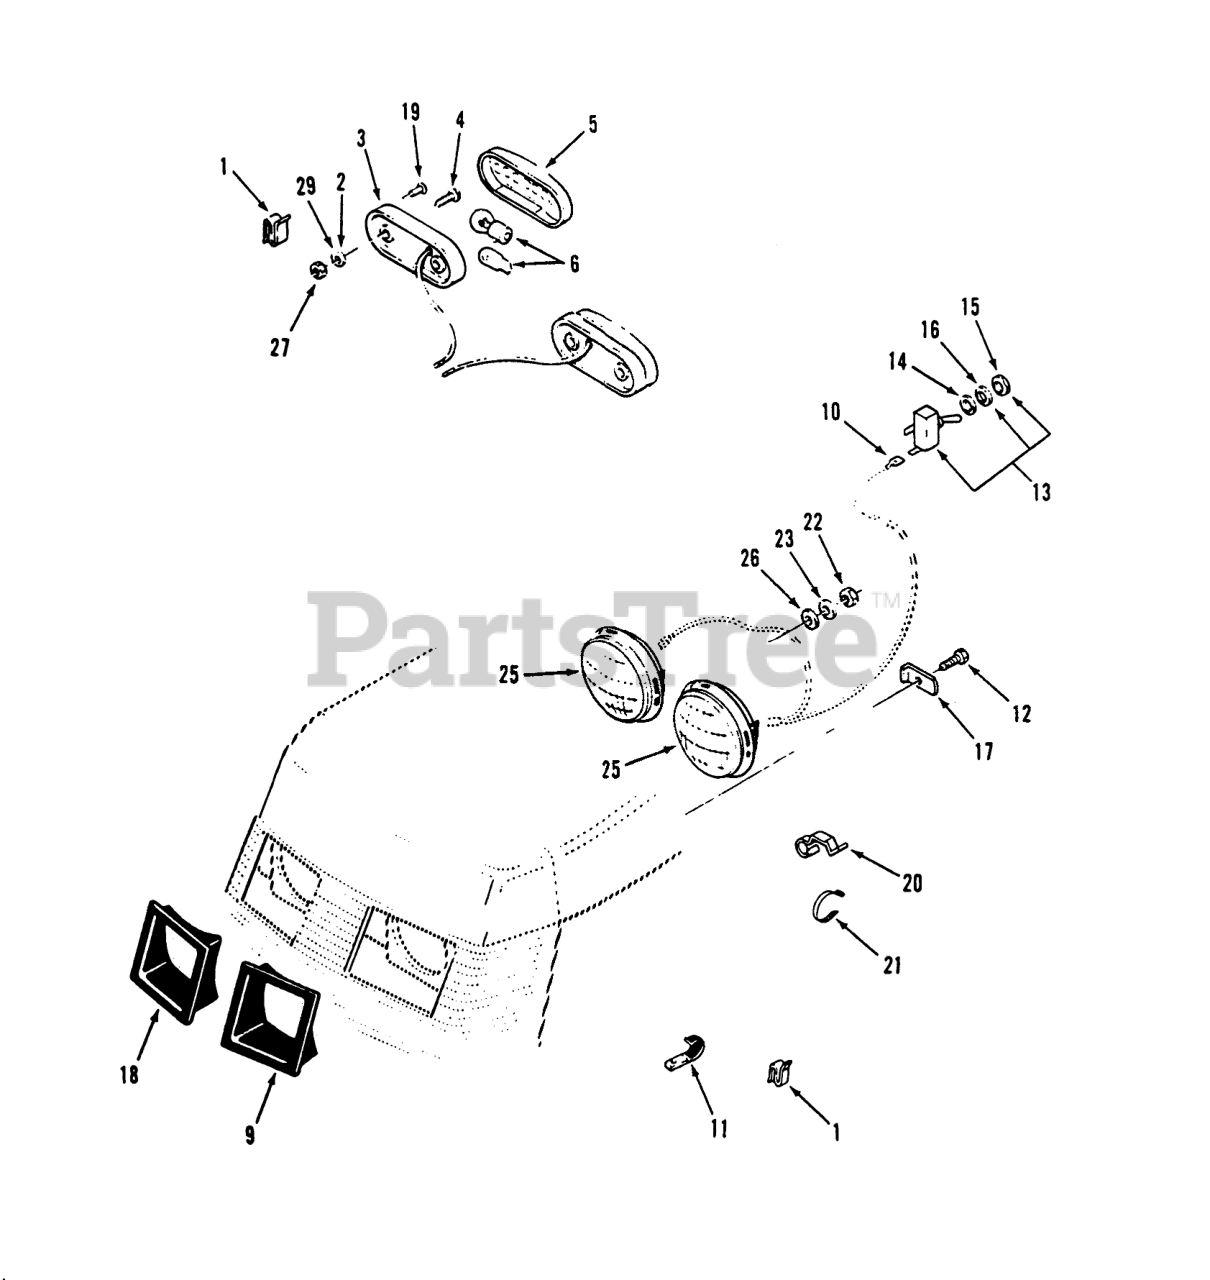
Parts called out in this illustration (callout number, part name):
1	SPEED CLIP
2	WASHER-LOCK
3	BASE-TAIL LIGHT
4	Screw
5	LENS-TAIL LIGHT
6	Bulb
9	BEZEL-HEADLIGHT, LH
10	Terminal
11	CLIP
12	Bolt
13	SWITCH-LIGHTS
14	Washer
16	TAB-WASHER
17	LOCK-HEADLIGHT
18	BEZEL-HEADLIGHT, RH
19	RIVET-POP
20	CLIP-WIRE
21	PLASTIC TIE
22	NUT-LOCK, NI
23	WASHER-LOCK, INTERNAL
25	HEADLAMP
26	WASHER-PLAIN
27	Nut
29	WASHER-FLAT
